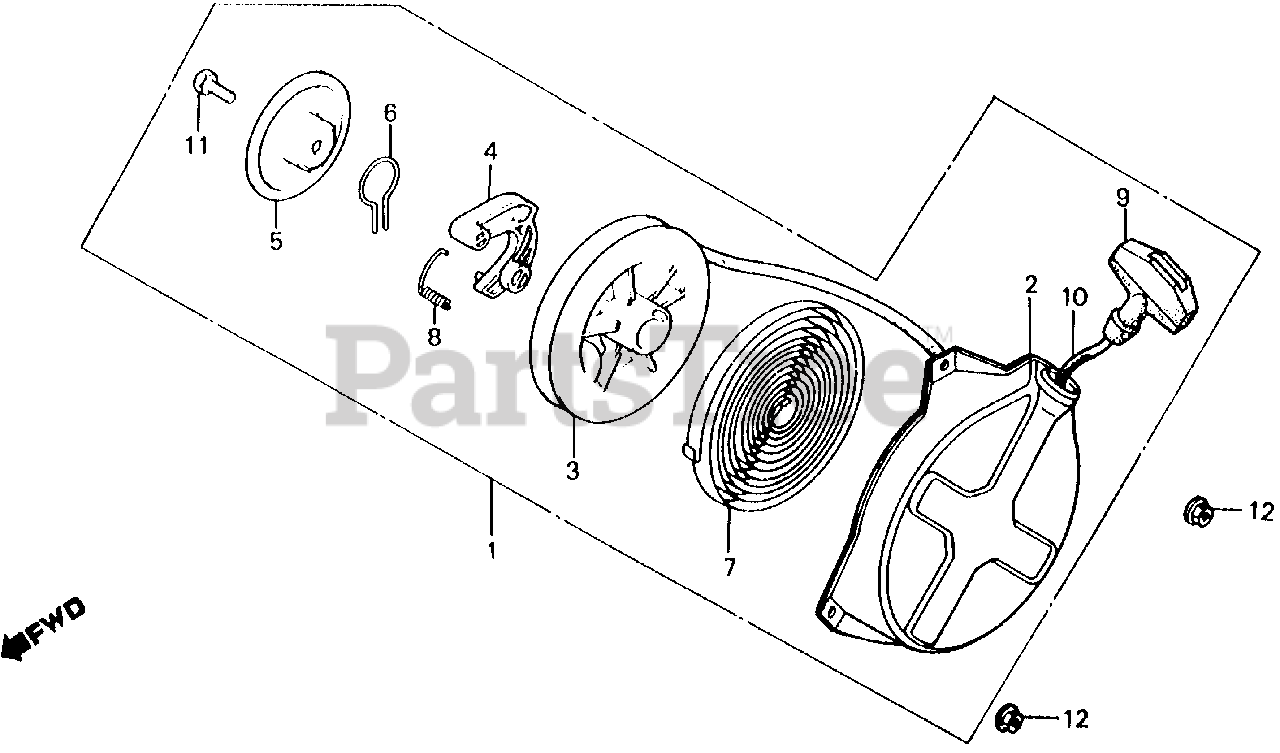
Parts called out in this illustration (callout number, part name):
1	STARTER ASSY., RECOIL (NOT AVAILABLE)
2	CASE, RECOIL STARTER
3	PULLEY, RECOIL STARTER (NOT AVAILABLE)
4	RATCHET, STARTER
5	PLATE, FRICTION
6	SPRING, FRICTION
7	SPRING, RETURN
8	SPRING, RETURN
9	KNOB, STARTER
10	ROPE, RECOIL STARTER (#4X55")
10	ROPE (#4X55")
11	BOLT, HEX. (6X20)
12	NUT, FLANGE (6MM)
